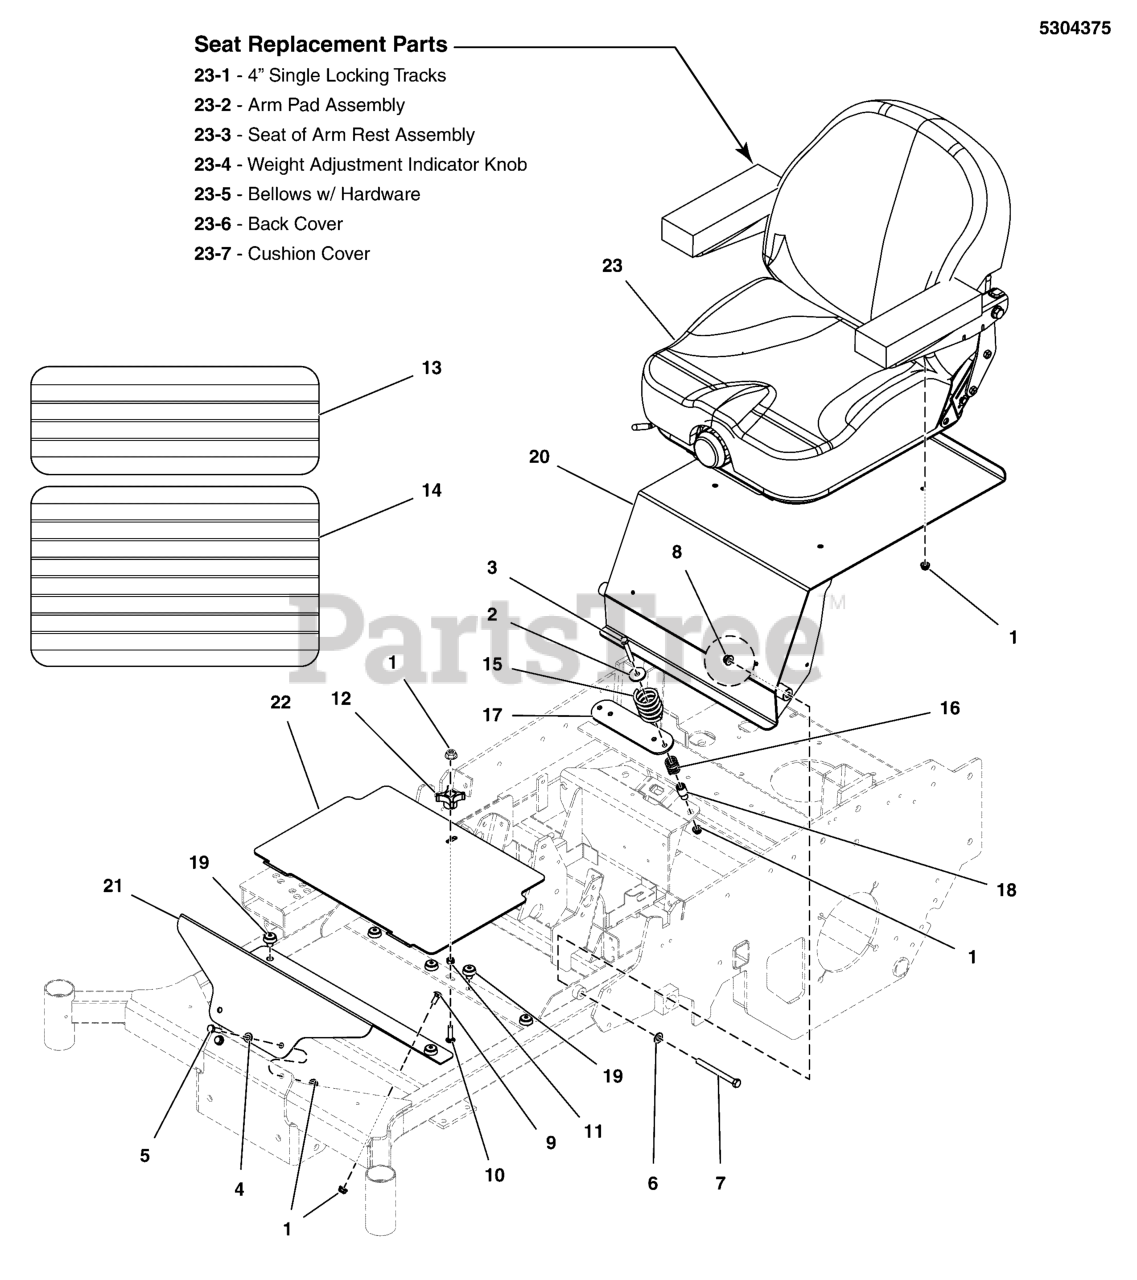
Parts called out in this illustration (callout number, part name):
1	NUT, 5/16-18 HEX NYLOCK FLANGE
2	WASHER, .34 X 1.25 X 10 GA
3	BOLT, 5/16-18 X 2-1/4 GD5 YZ
4	WASHER, 5/16" SAE
5	BOLT, 5/16-18 X 1 GD5 YZ
6	WASHER, 3/8 SAE
7	BOLT, 3/8-16 X 4" GD5 CZ
8	NUT, 3/8-16 HEX NYLOCK FLANGE
9	BOLT, 5/16-18 X 3/4, CARRIAGE
10	BOLT, 5/16-18 X 1-1/4, CARRIAGE YZ
11	NUT, 5/16-18, HEX, CNTR LK,ZINC PHOS/OIL
12	KNOB-INT THR .312-18 4-ARM 2.12WD 1.06LG
13	SAFETY WALK, FLOOR REST, 6.00 X 16.00
14	SAFETY WALK, FLOOR PLATE, S50X, 10X16
15	SPRING, SEAT SUPPORT
16	SPRING, COMP 720ID X 1.310LG X .118WIRE
17	PLATE, SEAT SWITCH - RED
18	SPACER, .33 X .66 X 1.31 SHLDR, CZ
19	MNT, VBRTN, RBBR
20	ASSM, SEAT PLATE W/DECALS, F160Z-DOM (5413405B)
21	PLATE, FLOOR, NON REMOVABLE - RED
22	PLATE, FLOOR, REMOVABLE, IS700 - RED
23	SEAT, MID BACK W/SUSPENSION, SEATS INC
23-1	4" SINGLE LOCKING TRACKS BASE
23-2	ARM PAD ASSEMBLY BLK/CHAR CAR FIB/HARBR GRY RED WELT
23-3	SET OF ARMREST ASSEMBLY BLK/CHAR CAR FIB/HARBR GRY RED WELT
23-4	WEIGHT ADJUST INDICATOR KNOB ASSY BASE
23-5	BELLOWS W/ HARDWARE BASE
23-6	BACK COVER FOR FIXED BACK I3M BLK/CHAR CAR FIB/HARBR GRY RED WELT
23-7	CUSHION COVER FOR I3M BLK/CHAR CAR FIB/HARBR GRY RED WELT
